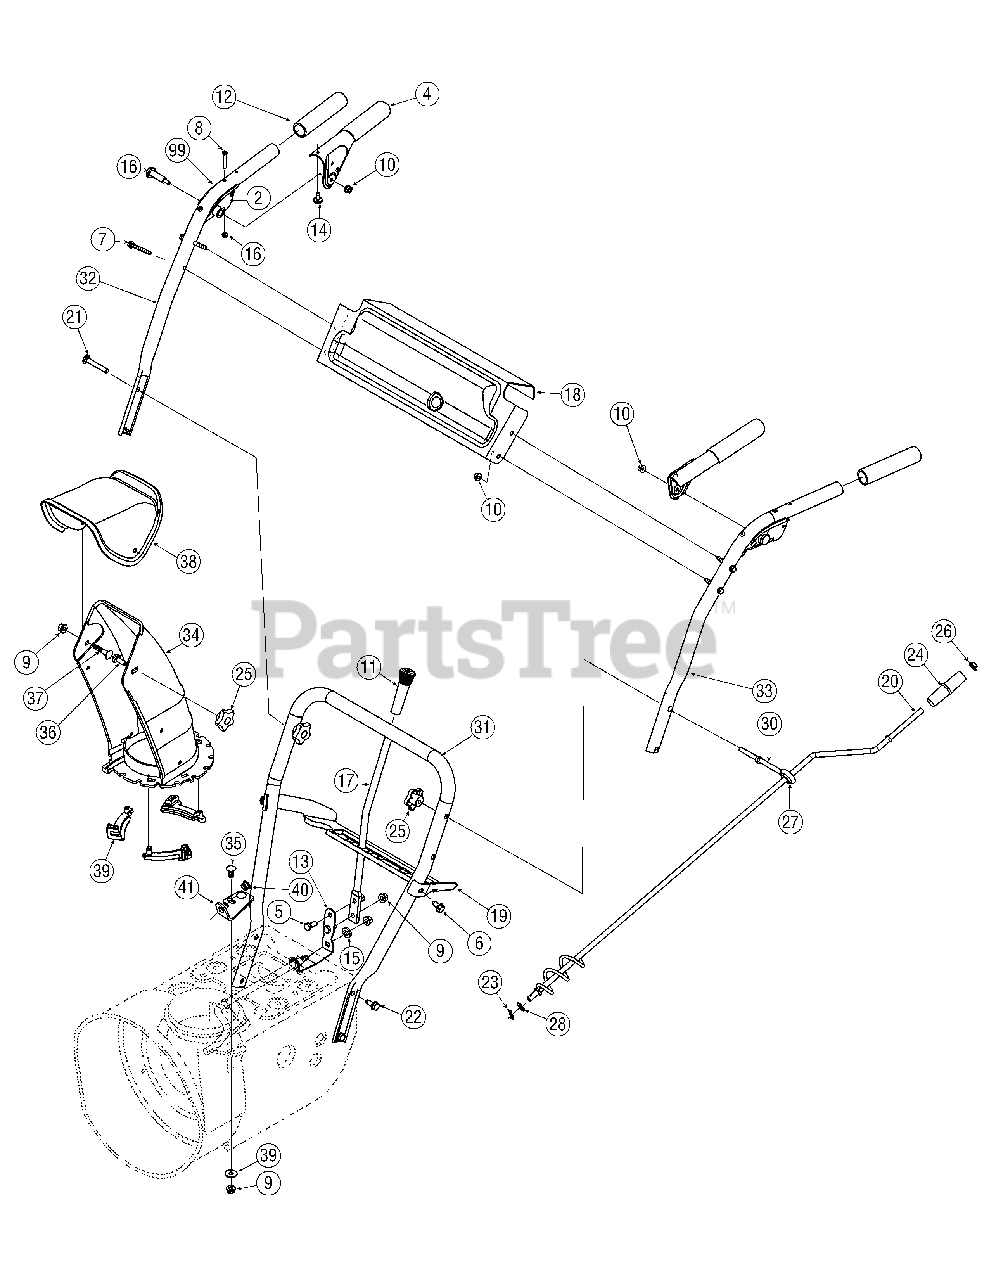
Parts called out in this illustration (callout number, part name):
1	Handle Ass’y, Lock LH
2	Handle Ass’y, Lock, RH
3	Handle Ass’y, Engagement LH
4	Handle Ass’y, Engagement, RH
5	Screw, Self-tapping, 5/16-18, .625
6	Screw, Self-tapping, 5/16-18, 1.0
7	Screw, Self-tapping, 1/4-20, 1.50
8	Screw, Machine, #10-24, 1.375
9	Nut, Flange Lock, 5/16-18, Nylon
10	Nut, Flange Lock, 1/4-20, Nylon
11	Grip, 0.5 ID x 3.45
12	Grip, 1.0 ID x 5.0
13	Spring Lever, Shift
14	Bumper, Rubber, .62 OD x .22
15	Washer, Flat, .469 x .875 x .105
16	Screw, Shoulder, 1/4-20, .437
21	Screw, Carriage, 5/16-18, 2.25
22	Screw, 5/16-18, 0.75, Gr5
23	Pin, Cotter, .072 x 1.13
24	Crank Knob, 1.0 Dia. x 3.2, Black
25	Knob Assembly, Black, 5/16-18
26	Cap, Push, 3/8 Rod
27	Grommet, .44 ID x .94 OD x .50
28	Washer, Flat, .375 x .738 x .063
29	Washer, Saddle, 320 x .93 x .060
30	Eye Bolt, Chute Crank
34	Chute, Lower, 5.0 Diameter
35	Bolt, Carriage, 5/16-18, 1.0
36	Bolt, Carriage, 5/16-18, 1.0
37	Bolt, Carriage, 5/16-18, .750
38	Chute, Upper, w/ Label
39	Chute, Flange Keeper
40	Bushing, Plastic, .380
